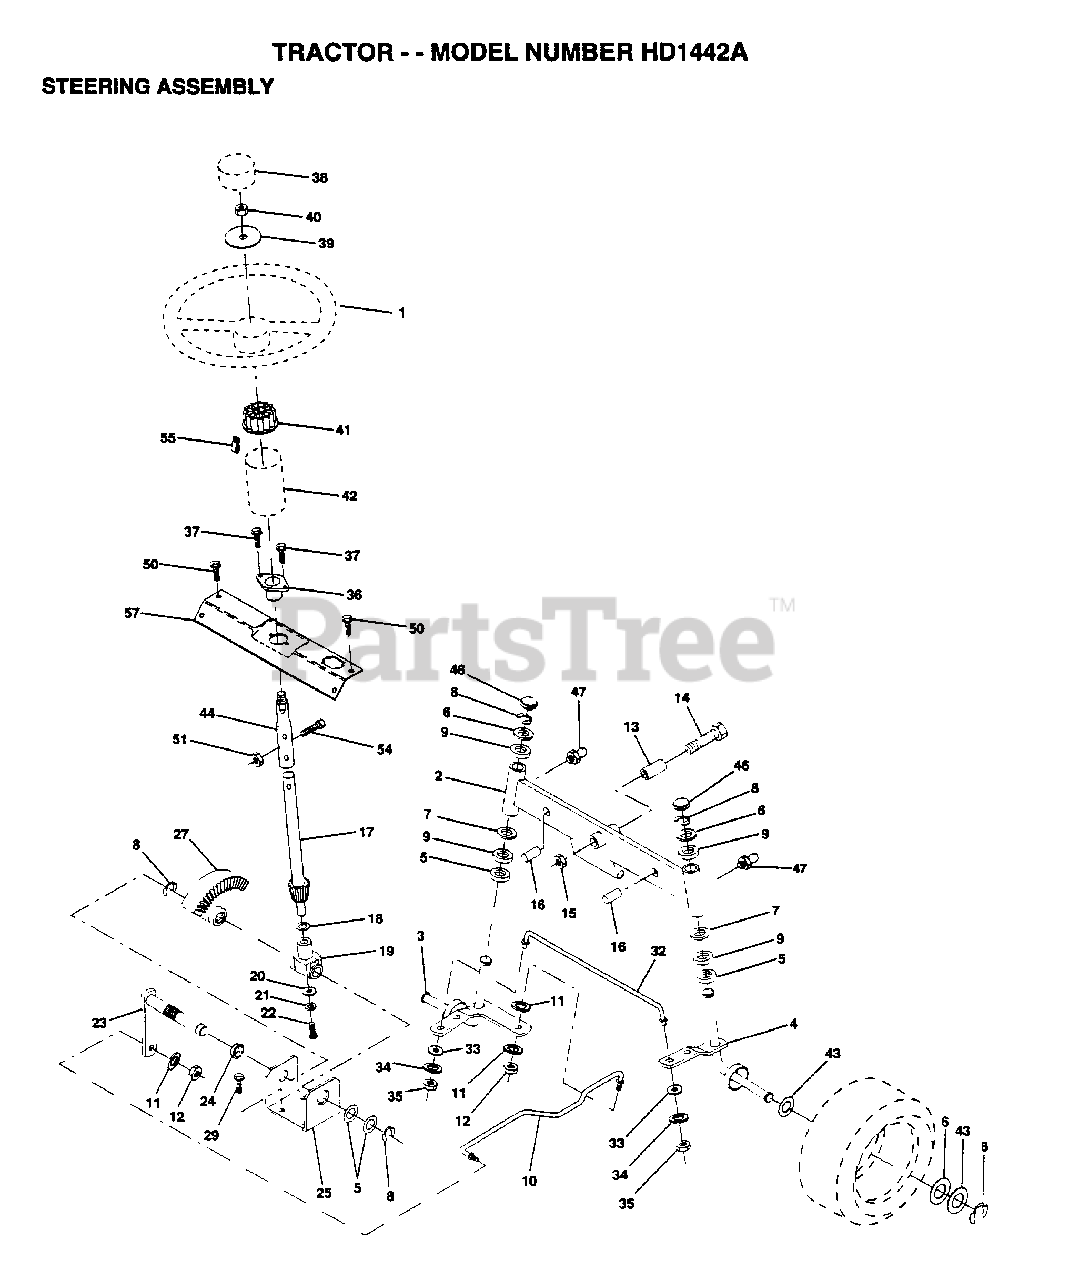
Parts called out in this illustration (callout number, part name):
1	WHEEL STR AYP BLK
2	AXLE ASM FRONT
3	SPINDLE LH
4	SPINDLE RH
5	WASHER .T
6	WASHER
7	WASHER
8	RING
9	COL. SRTG. BEAR.
11	LOCKWASHER
13	BEARING
14	BOLT HEX 5/8-11
15	"NUT-LOC,FLANGE LT"
16	AXLE PIN
17	SHAFT ASM STEERIN
18	THRUST WASHER
19	SUPPORT.SHAFT
21	LOCKWASHER
22	"SCREW,SPECIAL"
24	NYLINER T
25	"BRKT,STEERING"
27	GEAR SECTOR
29	SCREW
32	TIE ROD
33	WASHER M
34	LOCKWASHER
35	NUT.LOCK.5/16-24
38	CAP STEER AYP
39	WASHER T
40	GRIPCO NUT
41	ADAPTER-WHEEL LT
42	BOOT SHAFT STEER
43	WASHER
44	SHAFT EXT STEER
46	CAP
47	ZERK M
50	SCREW HEX CRT
51	NUT
54	BOLT
55	CLIP TINNERMAN
57	SUPPORT SHAFT STR
